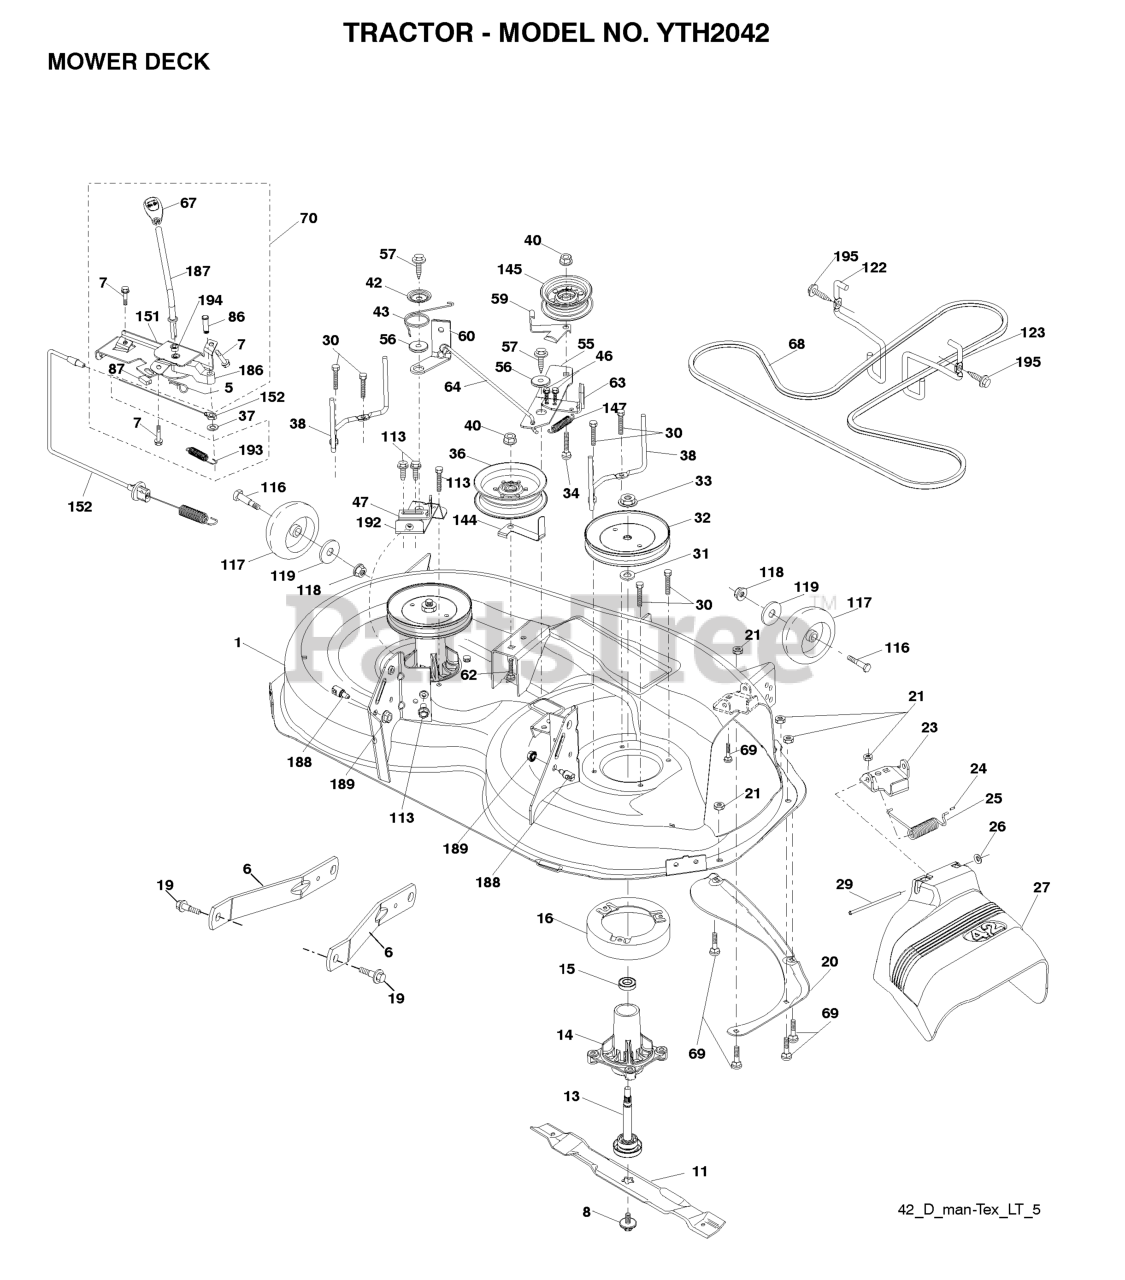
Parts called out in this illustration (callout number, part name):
1	DECK.WELDMENT.42"PAINT
5	RETAINER-SPRNG RB
6	ARM.SUSPENSION.MOWER.R
7	SCREW
8	BOLT.WASHER.ASM.7/16-2
11	42" HI-LIFT BLADE
13	SHAFT.ASM.MDRL.N/GREASE.38
14	RP.HOUSING.MANDREL.4PT.
16	STRIPPER.MANDREL.ROUND.BLACK
19	BOLT.SHOULDER
20	BAFFLE.VORTEX
21	LOCKNUT
23	BRKT.DEFLECTOR.38"2005+
24	CAP-SLEEVE LT
25	SPRING.TORSION.DEFLECT
26	NUT PUSH M
27	SHIELD.DEFLECTOR.MOWER.42"BLAC
29	ROD.HINGE
30	SCREW, WASHER HEAD
31	WASHER.SPACER.MANDREL
32	PULLEY.MANDREL.5.438.P
33	NUT.FLANGE.LOCK.TOP
34	BOLT.3/8-16X1.50
36	PULLEY.IDLER.2006
37	WASHER
38	KEEPER.BELT.LH.MANDREL
40	NUT LOCK FLG 3/8-16 UNC
42	SPRING.TORSION.BRAKE
43	SRPING.TORSION.RETAINE
46	SCREW.1/4-20X5/8
47	BRKT.CLUTCH.CABLE
56	SPACER.RETAINER
57	SCREW 3/8-16X1
59	GUARD, BELT
60	ARM BRAKE MOWER
63	ARM.BRAKE.ZINC
64	LINKAGE.BRAKE.ASM.ZINC
67	HANDLE.CLUTCH.CABLE.LT
68	BELT.DRIVE.MOWER.TEX.42"
69	BOLT
70	CLUTCH.ASM.CABLE.HUSQ.TEX
86	PIN ATTACHMENT CABLE
87	SWITCH.INTRLCK.CLUTCH.
113	BOLT.5/16HEX.WHS.HD
115	BOLT.CARR.5/16-18X5/8.SHORT
116	BOLT.SHOULDER.3/8-16X3-5/8.
117	RP WHEEL. GUAGE RALLY
118	LOCKNUT
119	WASHER
122	KEEPER BELT ENGINE LH
123	KEEPER BELT RH
144	KEEPER.BELT.MOWER
145	PULLEY.IDLER.FLAT
147	RETURN SPRING
152	CABLE CLUTCH MANUAL W/SPR.
186	ARM ACTUATOR
188	STUD.FASTNER.W/ANTI-ROTATE
189	NUT LOCK HEX FLANGE 5/16-18
192	BRKT.BRAKE.STAND.LH.
193	SPRING.PLUNGER.ACTUATOR
194	BEARING.CONTROL.LEVER.CLUTCH
195	SCREW, 3/8-16X3/4
